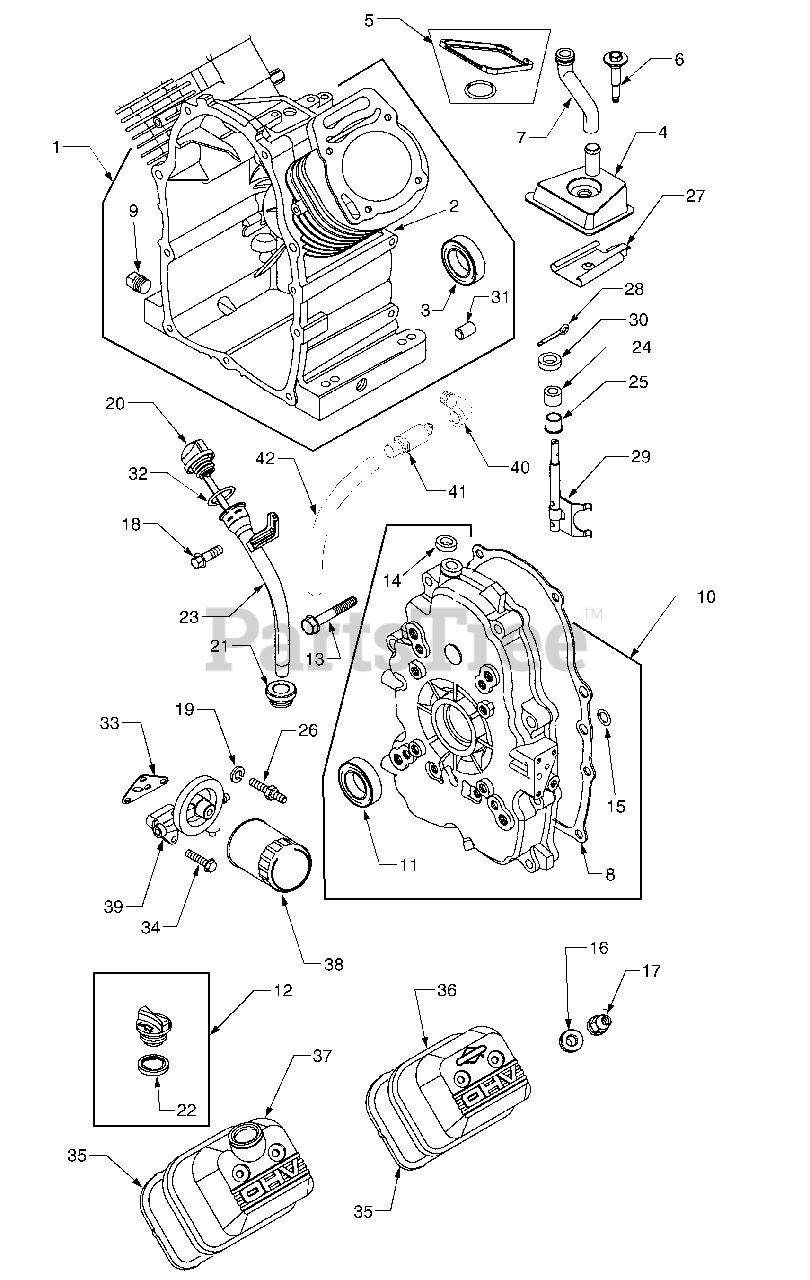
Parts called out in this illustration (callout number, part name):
1	Cylinder Assembly
2	Bearing, Cylinder
3	Seal, Oil
4	Breather Assembly
5	Gasket, Breather
6	Screw, Hex
7	Tube, Breather
8	Gasket, Crankcase Cover
9	Plug, Oil Drain
10	Cover, Crankcase
11	Seal, Oil
12	Plug, Oil Fill
13	Screw, Crankcase Cover Mtg.
14	Seal, Governor Shaft
15	Seal, O-Ring
16	Washer
17	Nut, Nylock
18	Screw, Hex
19	Washer, Lock
20	Cap and Dipstick - Oil Fill
21	Seal, Fill Tube
22	Seal, Fill Plug
23	Tube, Oil Fill
24	Bushing, Governor Shaft
25	Bushing, Governor Shaft
26	Stud, Oil Filter Adapter
27	Baffle, Breather
28	Pin, Cotter
29	Crank, Governor
30	Washer, Governor Shaft
31	Dowel Crankcase
32	Seal, O-Ring
33	Gasket, Filter Adapter
34	Screw, Hex
35	Gasket, Rocker Cover
36	Cover, Rocker
37	Cover, Rocker
38	Filter, Oil
39	Adapter, Filter
40	Elbow, 90 Degree
41	Drain, Oil
42	Hose, Oil Drain
